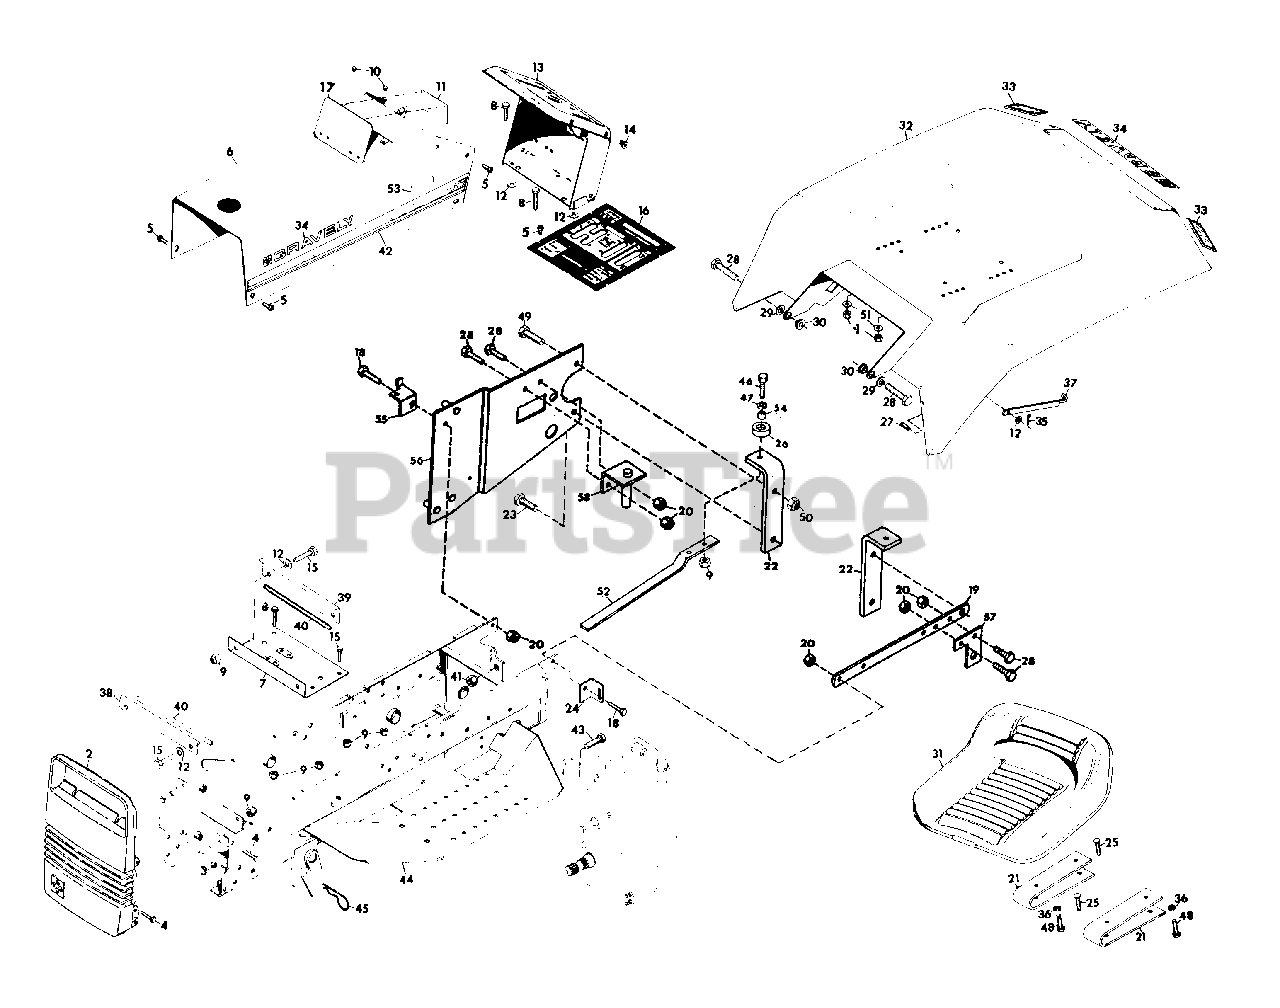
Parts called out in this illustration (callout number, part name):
1	NUT, LOCK 5/16-18
2	CASTING, GRILLE
3	NUT, LOCK 5/16-18
4	BOLT, HEX 5/16-18X1.25
5	SCREW, MACHINE 1/4-20X.5 PAN HD CR
6	ASM, HOOD 8122, 8123 AND 8163-B
6	ASM, HOOD 8179-KT AND 8199-KT
7	TRAY, BATTERY
8	BOLT, HEX 1/4-20X.625
9	NUT, LOCK 1/4-20
10	PLUG, BUMPER
11	DECAL, ELECTRICAL SYSTEM WARNING
12	WASHER, FLAT .281X.625X.065
13	PANEL, INST. 8122, 8123 AND 8163-B
13	PANEL, INST. 8179-KT AND 8199-KT
14	GROMMET, PLASTIC
15	BOLT, HEX 1/4-20X.875
16	PLATE, CONTROL COVER 8122
16	PLATE, COVER 8123 AND 8163-B
16	PLATE, COVER 8179-KT AND 8199-KT
17	ASSEMBLY, DOOR
18	BOLT, HEX 3/8-16X1.25
19	STRAP, FRAME EXTENSION
20	NUT, LOCK 3/8-16
21	SPRING, SEAT
22	BRACKET, REAR HITCH
23	BOLT, HEX 1/2-13X1.25
24	BRACKET, FENDER HOLD-UP
25	BOLT, 5/16-18X.75 RD HD SQ NK
26	BUMPER, SEAT
27	PIN, CLEVIS .250X.500
28	BOLT, HEX 3/8-16X1
29	WASHER, FLAT .406X.812X.065
30	BUSHING, REAR FENDER
31	SEAT, INTERMEDIATE BACK
31	SEAT, HIGH BACK
32	WELDMENT, SEAT PAN
32	WELDMENT, SEAT PAN W/NOTCH
33	REFLECTOR, RED SAFETY
34	DECAL, GRAVELY LOGO
35	PIN, COTTER .09X.625
36	WASHER, LOCK 5/16 SP
37	STRAP, FENDER HOLD-UP
38	BRACKET, FORWARD TANK
39	BRACKET, REAR TANK
40	MOULDING
41	NUT(RIM)
42	STRIPES, SIDE 8122, 8123 AND 8163-B
42	STRIPES, SIDE 8179-KT AND 8199-KT
43	BOLT, HEX 1/2-20X1.5
44	WLDMT, FRAME 8122, 8123 AND 8163-B
44	WLDMT, FRAME 8179-KT AND 8199-KT
45	COTTER, HAIR PIN
46	BOLT, HEX 1/4-20X1.50
47	WASHER, FLAT .312X.734X.065
48	BOLT, HEX 5/16-18X.75
49	BOLT, HEX 1/2-13X1.5
50	NUT, LOCK 1/2-13
51	WASHER, FLAT .375X1.125X.065
52	SPRING, CLUTCH DETENT
53	DECAL, 8122
53	DECAL, 8123
53	DECAL, 8179-KT
53	DECAL, 8163-B
53	DECAL, 8199-KT
54	BUSHING, .259X.375X.25
55	BRACKET, INTERLOCK SWITCH
56	WELDMENT, FWD-REV MTG. PLATE
57	BRACKET, CLUTCH SLIDE ROD
58	WELDMENT, CLUTCH ARM BRACKET
